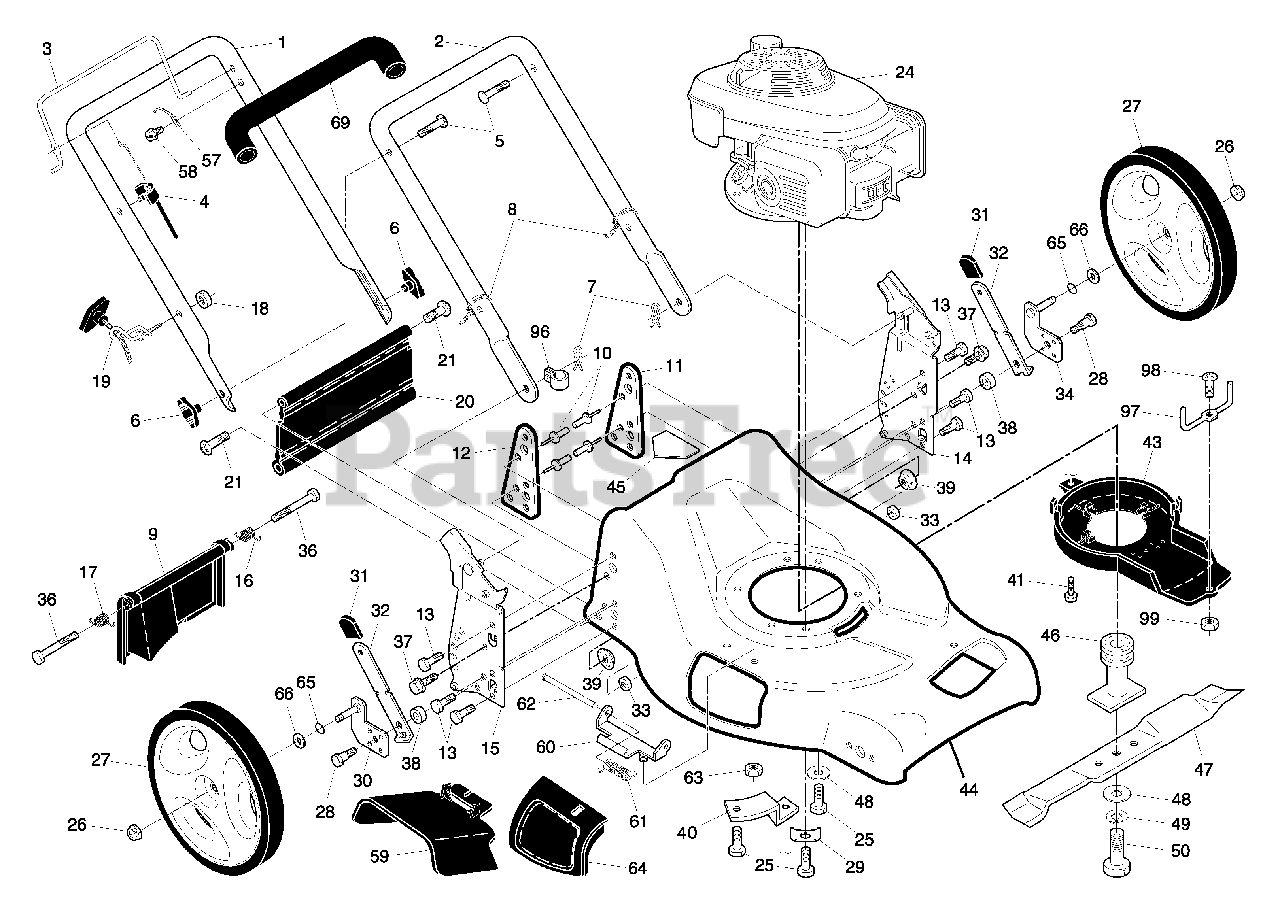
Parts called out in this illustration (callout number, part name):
1	Upper Handle, with Foam Grip
2	Lower Handle
3	Control Bar
4	Engine Zone Control Cable
5	Handle Bolt
6	Handle Knob
7	Hairpin Cotter
8	Wire Tie
9	Rear Door Assembly
11	Support Bracket, LH
12	Support Bracket, RH
13	Screw 1/4-20 x 5/8
14	Handle Bracket Assembly, LH
15	Handle Bracket Assembly, RH
16	Spring, Rear Door, LH
17	Spring, Rear Door, RH
18	Keps Locknut 1/4-20
19	Rope Guide
20	Rear Skirt
21	Screw, Hinge 1/4-20 x 1/2
25	Hex Head Thread Rolling Screw 3/8-16 x 1-1/8
26	Hex Flange Nut
27	Wheel & Tire Assembly, Rear, 12
28	Shoulder Bolt 5/16-18 x .33
29	Washer, Engine, Zinc-Plated
30	Axle Arm Assembly, Rear, RH
31	Selector Knob
32	Selector Spring
33	Nut,Hex 5/16-18
34	Axle Arm Assembly, Rear, LH
37	Thread Cutting Screw w/Sems 5/16-18 x 3/4
39	Nut, Hex, Flangelock 5/16-18
40	Mounting Bracket, Debris Shield
43	Debris Shield
44	Kit, Lawn Mower Housing
45	Danger Decal
46	Blade Adapter / Pulley
47	Blade, 21"
48	Hardened Washer
49	Helical Washer 3/8-24 x 1-3/8 Grade 8
50	Hex Head Machine Screw 3/8-24 x 1-3/8 Grade 8
57	Upstop Bracket
59	Discharge Deflector
60	Hinge Bracket
63	Nut, Hex
64	Mulcher Door
66	Washer, Flat 1/2
69	Grip, Foam
96	Clip, Cable
97	Belt Keeper
